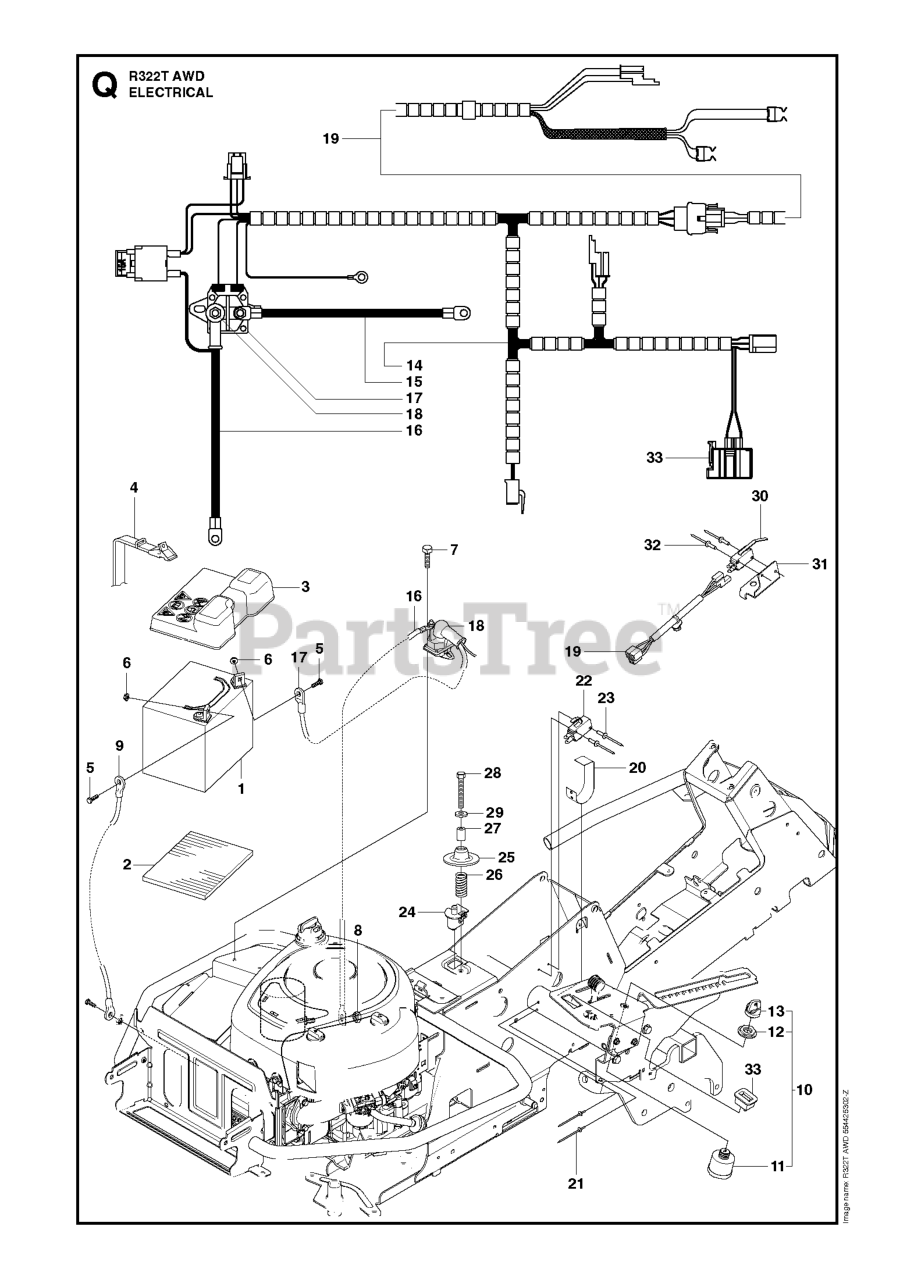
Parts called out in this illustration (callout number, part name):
5	SCREW EHHM
10	IGNITION SWITCH
11	IGNITION SWITCH
13	IGNITION KEY
16	CABLE
27	SPACER TUBE
28	SCREW
29	WASHER BRB 8.4X17
30	MICRO SWITCH
33	HOUR METER
